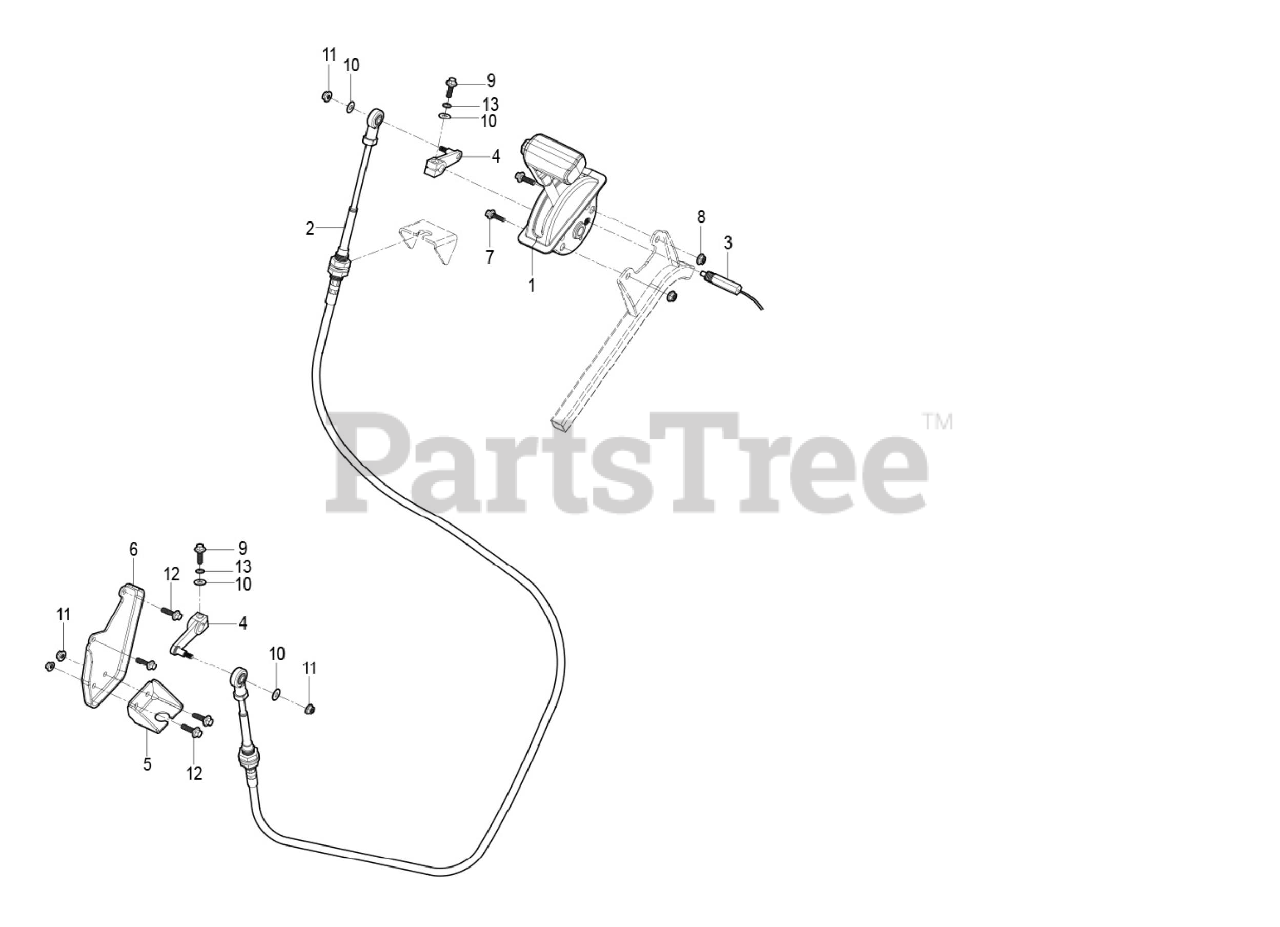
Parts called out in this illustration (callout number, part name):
1	GEAR SELECTOR ASSEMBLY
2	GEAR SELECTOR CABLE M
3	REVERSE CABLE CONTROL
4	GEAR SELECTOR ARM
5	GEAR SELECTOR CABLE BRACKET PLATED
6	GEAR SELECTOR BRACKET PLATED
7	BOLT HExAGON FLANGE HEAD M8x50
8	LOCK NUT M8
9	Flange Bolt M6x25
10	WASHER - FLAT
11	HExAGON FLANGE HEAD NUT M6
12	Hexagon Flange Bolt M6x16
13	WASHER - SPRING LOCK 8
